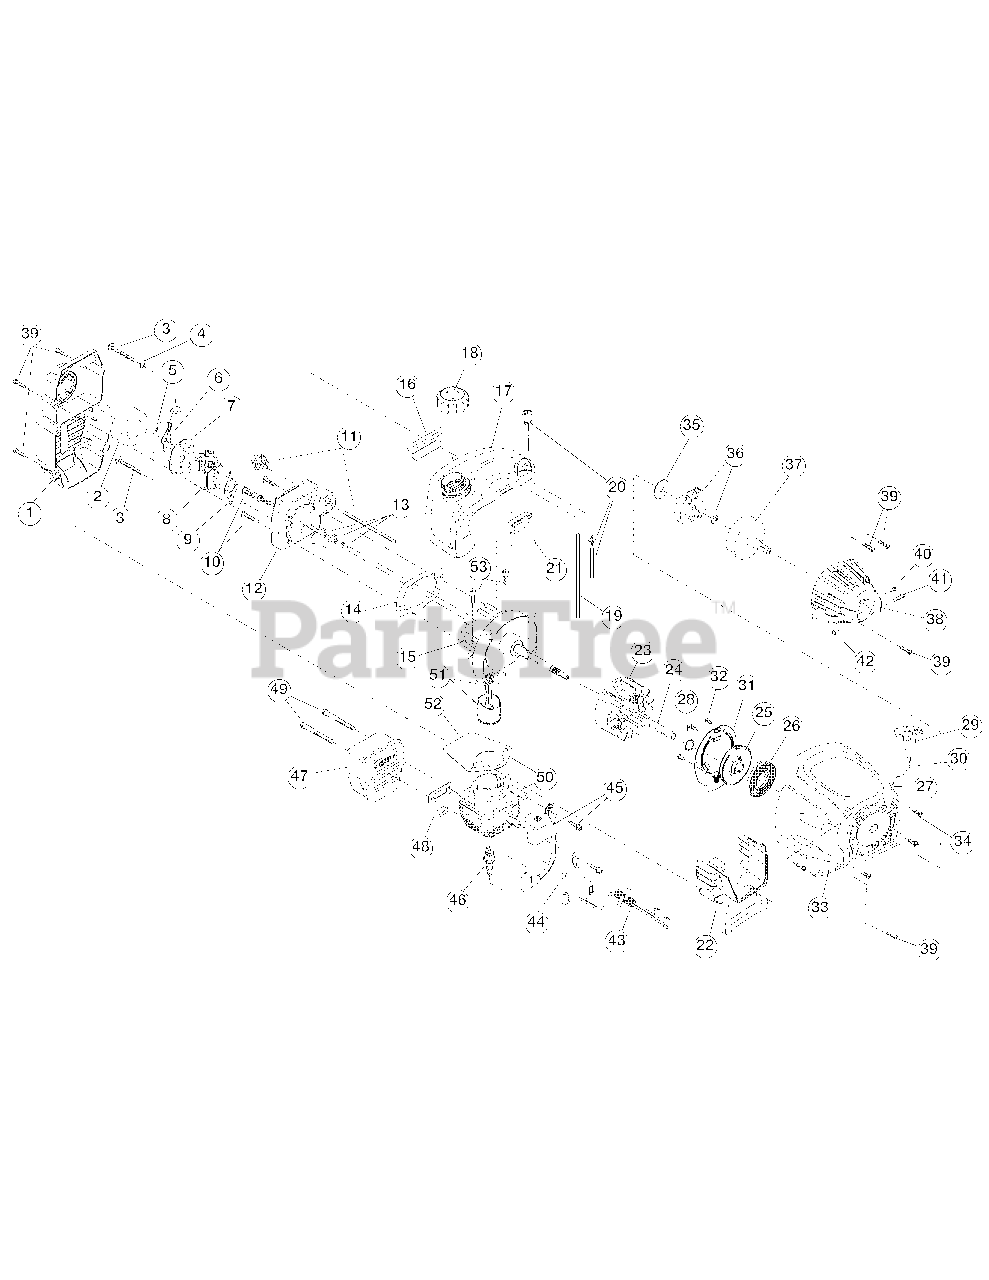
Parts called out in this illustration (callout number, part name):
1	Air Cleaner Cover Assembly (includes 2 & 39)
2	Air Cleaner Filter
3	Carburetor Mounting Screw Assembly
4	Wavey Washer
5	Choke Knob w/Screw
6	Choke Lever (includes 5)
7	Choke Plate (includes 6)
8	Carburetor Assembly (includes 9 & 20)
9	Carburetor Gasket
10	Carb Mount Screw
11	Primer & Hose Assembly
12	Carb Mount Assembly (includes 10, 13 & 14)
13	Reed Assembly
14	Carburetor Mount Gasket
15	Crankcase Service Assembly (includes 10)
16	Rear Mounting Pad
17	Fuel Tank Assembly (includes 18-20)
18	Fuel Cap Assembly
19	Fuel Return Line
20	Fuel Line Assembly
21	Front Mounting Pad
22	Shroud Extension & Stand (includes 39)
23	Flywheel Assembly
25	Recoil Pulley Assembly (includes 28 & 30)
26	Recoil Spring
27	Rope Guide
28	Pulley Retainer
29	Pull Handle
31	Pressure Plate Assembly (includes 32)
32	Plate Screw
33	Starter Housing Assembly
34	Housing Screw
35	Clutch Washer
36	Clutch Rotor Assembly
37	Clutch Drum Assembly
38	Clutch Cover Assembly (includes 39-42)
39	Cover Screw
40	Anti-Rotation Screw
41	Clamping Screw
42	Clamping Nut
43	Wire Leads and Sleeve
44	Ground Tab
45	Module Assembly
47	Muffler Assembly
48	Exhaust Gasket
49	Muffler Mounting Bolts
50	Cylinder Assembly (includes 52 & 53)
51	Piston and Rod Assembly
52	Cylinder Gasket
53	Cylinder Bolt
